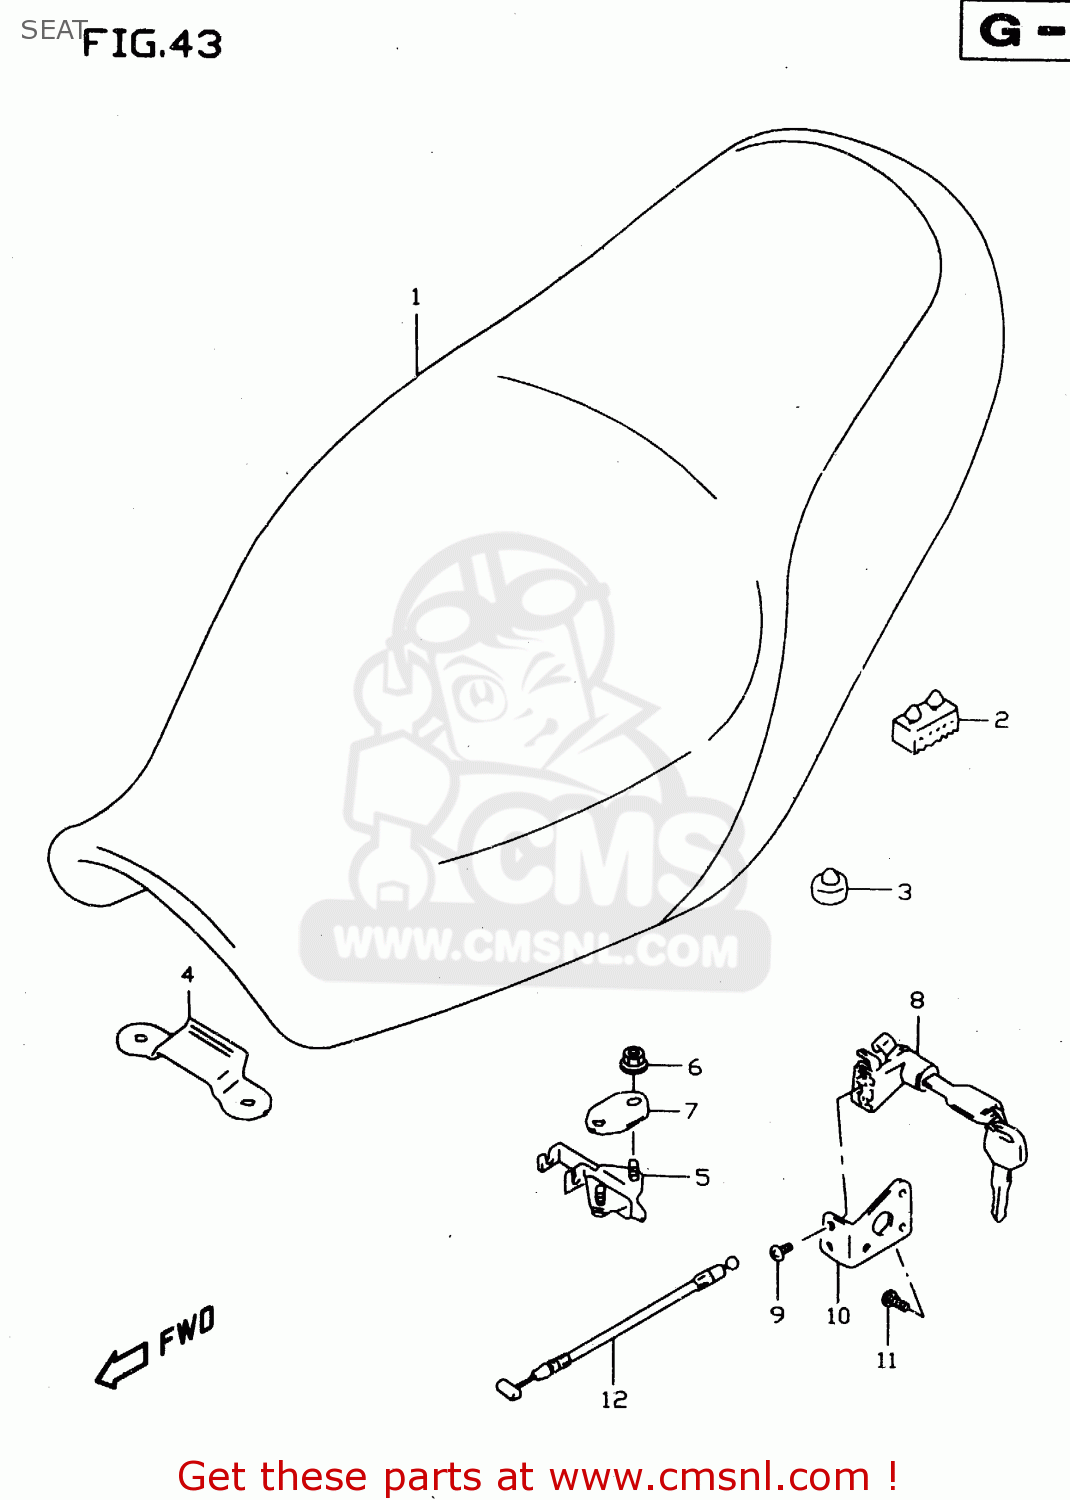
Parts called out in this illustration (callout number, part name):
1	SEAT ASSY
2	CUSHION,SEAT(40X20X15)
3	CUSHION
4	PLATE,SEAT HOOK FR
5	BRACKET,SEAT SUPPORT
6	NUT
7	PLATE,SEAT SUPPORT BRKT
8	LOCK SET,SEAT
9	BOLT
10	BRACKET,SEAT LOCK
11	SCREW
12	CABLE,SEAT LOCK
